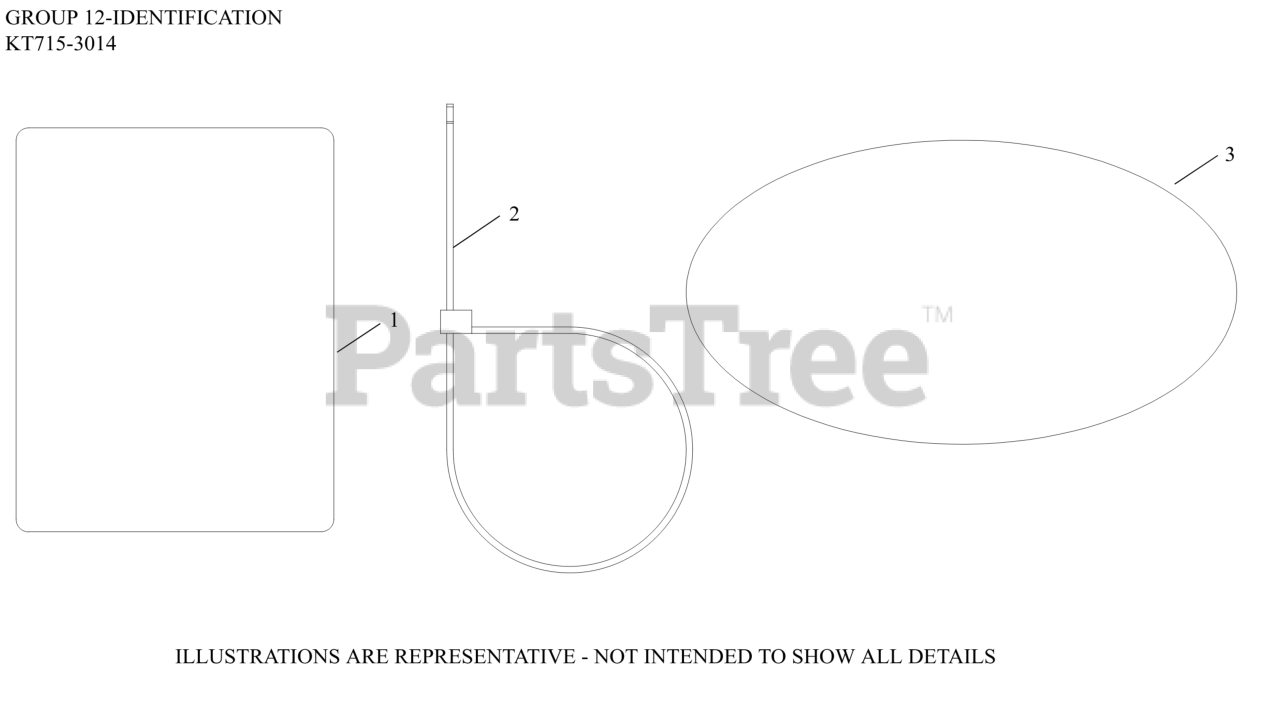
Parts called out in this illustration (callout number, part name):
1	LABEL, CLEAR LAMINATION
3	LABEL, 7000 SERIES (20HP, 3-YR LTD WTY)
3	LABEL, 7000 SERIES KT715 (20 HP)
